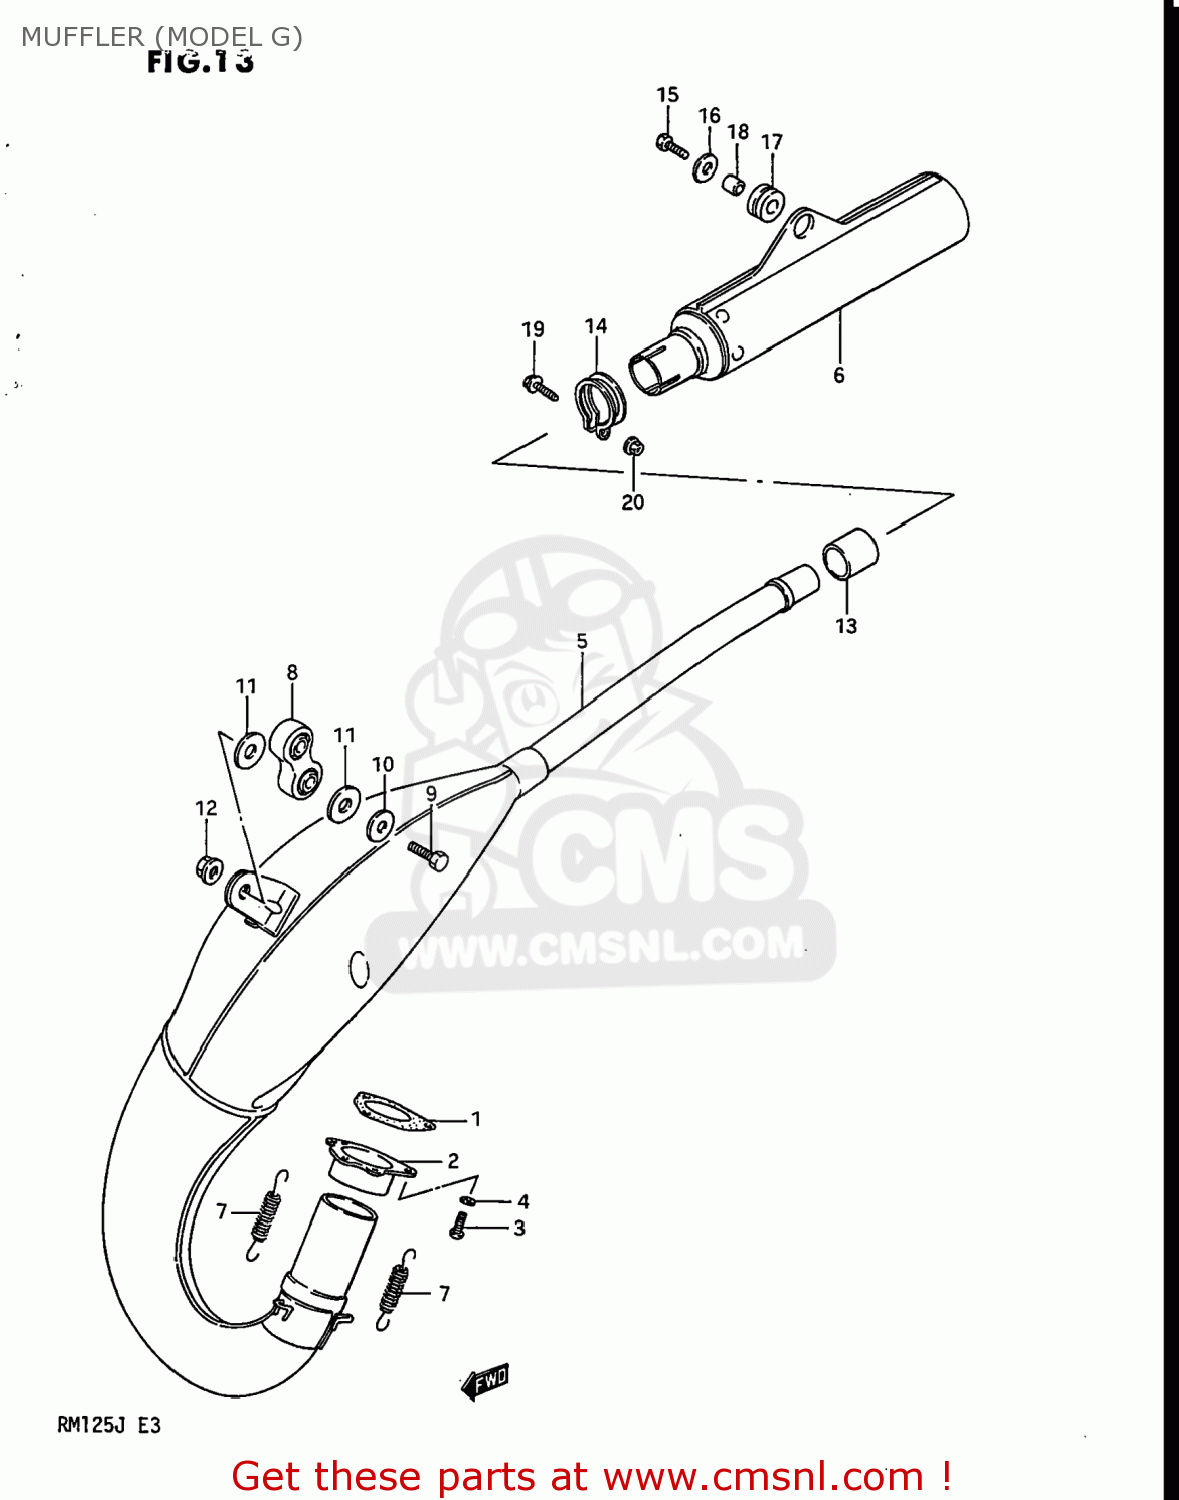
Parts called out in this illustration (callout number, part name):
1	GASKET,EXHAUST PIPE (MCA)
2	FLANGE COMP,EXHAUST PIPE
3	SCREW
4	WASHER,LOCK
5	BODY,MUFFLER,FIRST
6	BODY,MUFFLER
7	SPRING
8	DAMPER,MUFFLER
9	BOLT(8X32)
10	WASHER
11	WASHER(13X28X1.6)
12	NUT
13	GASKET,SECOND MUFFLER (NAS)
14	CLAMP,MUFFLER SECOND
15	BOLT 6X22
16	WASHER (6.5X24X1.6)
17	CUSHION
18	SPACER(6.3X9.1X11.5)
19	BOLT
20	NUT 6MM
